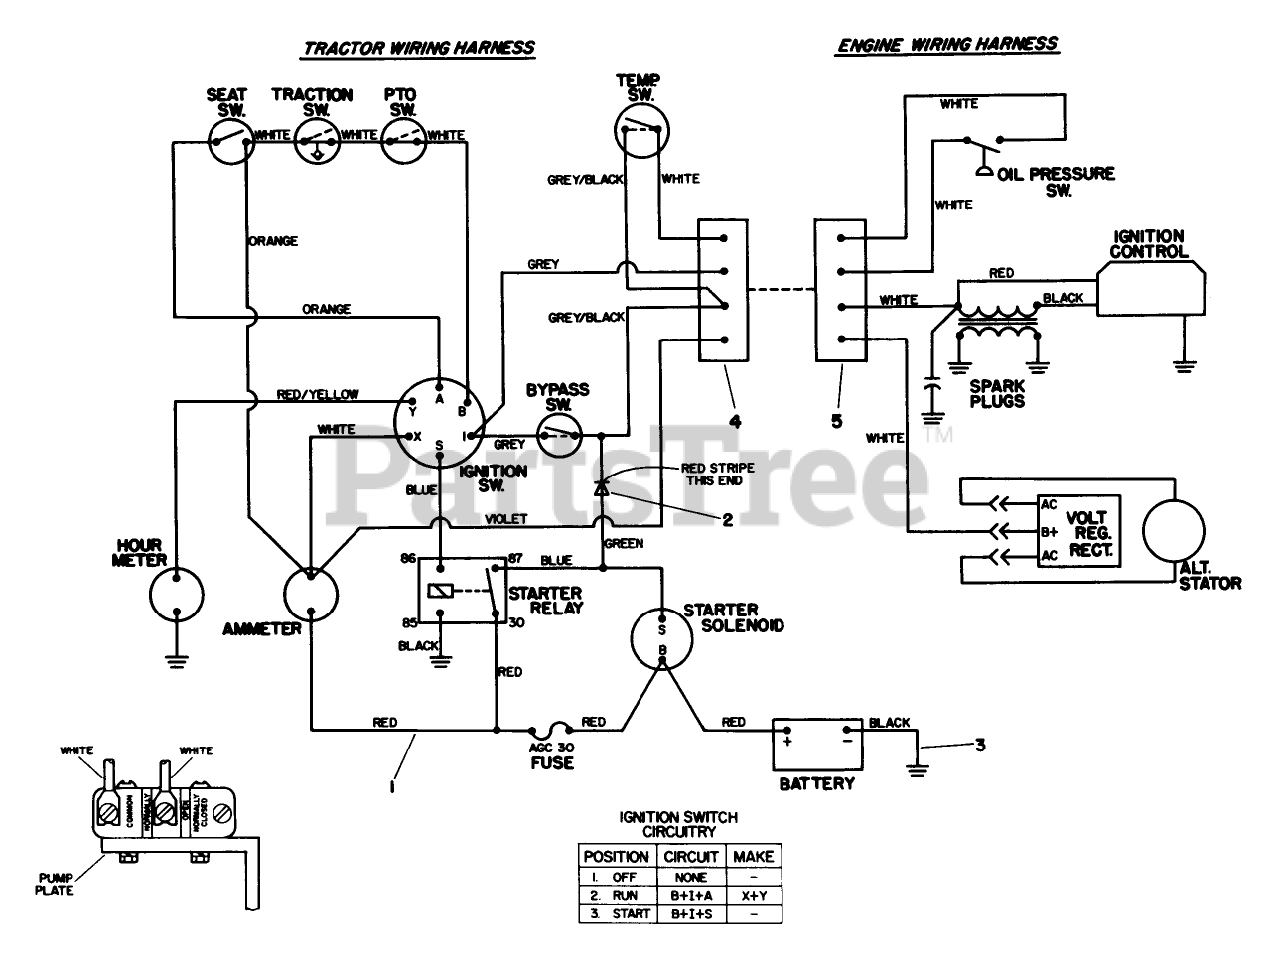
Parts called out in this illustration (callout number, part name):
1	Harness-Wire (Incl. Ref. #2)
2	DIODE ASM
3	BATTERY GROUND WIRE
4	TAB HOUSING
5	RECEPTACLE HOUSING
